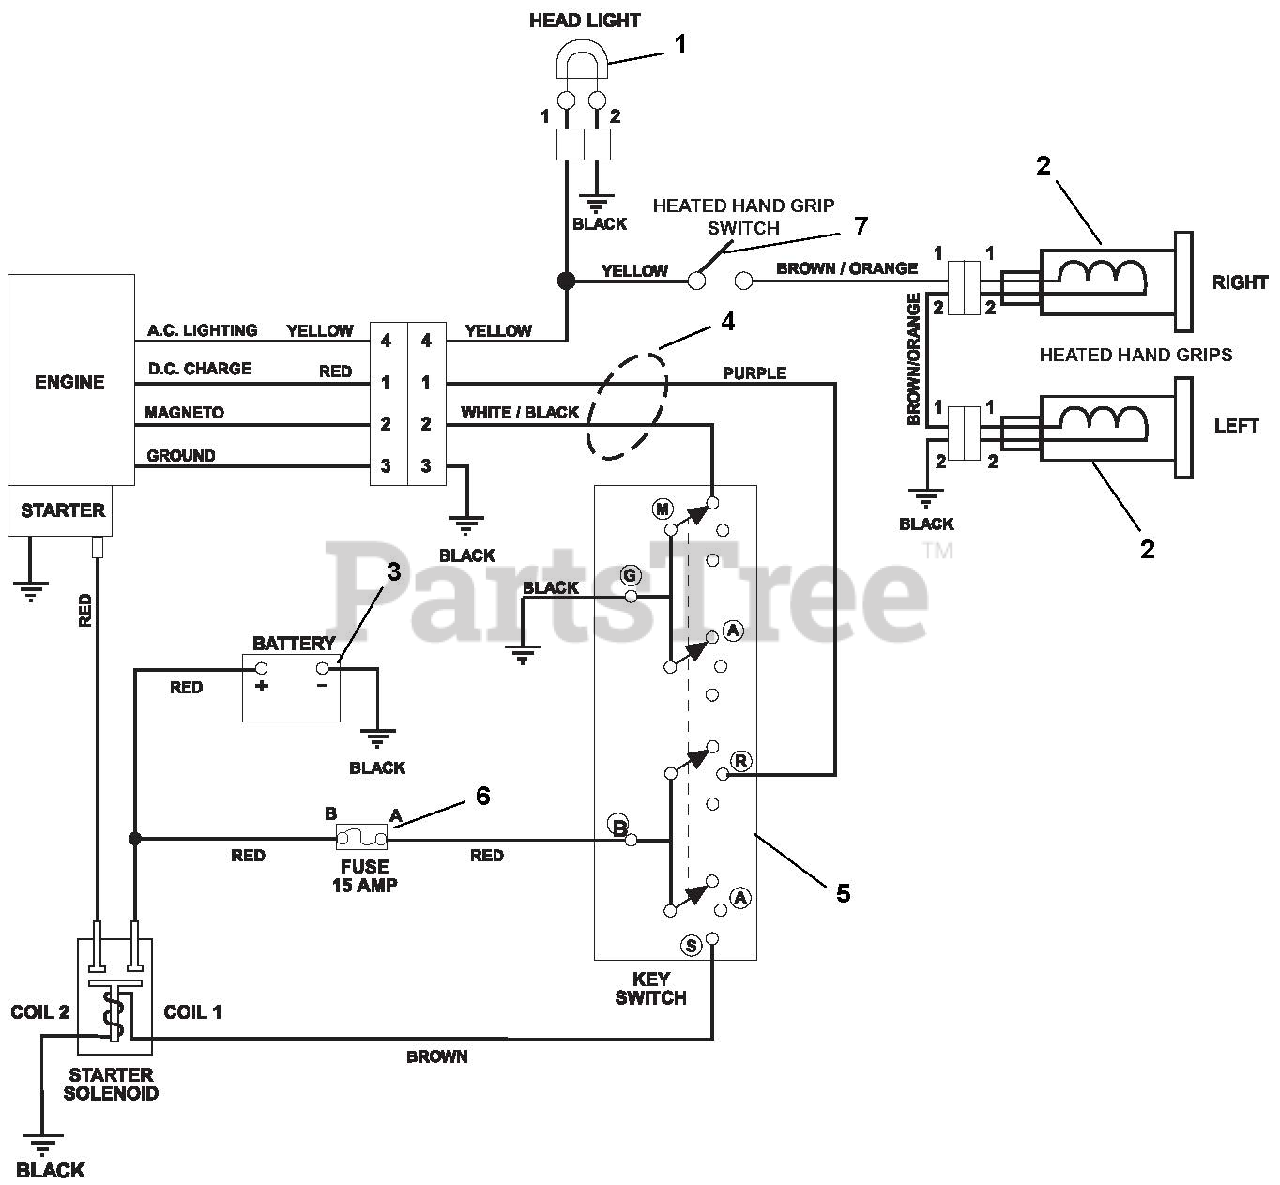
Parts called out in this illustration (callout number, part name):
1	HEADLIGHT ASY, HOLO 15W 2 SHOT
2	GRIP,HEATED HANDLE-GRAY
3	Battery
4	HARNESS,BRUSH-LT,HW,12V
5	SWITCH ASSEMBLY
6	FUSE, 15 AMP.
7	SWITCH,ROCKER SPST-ON/OFF
